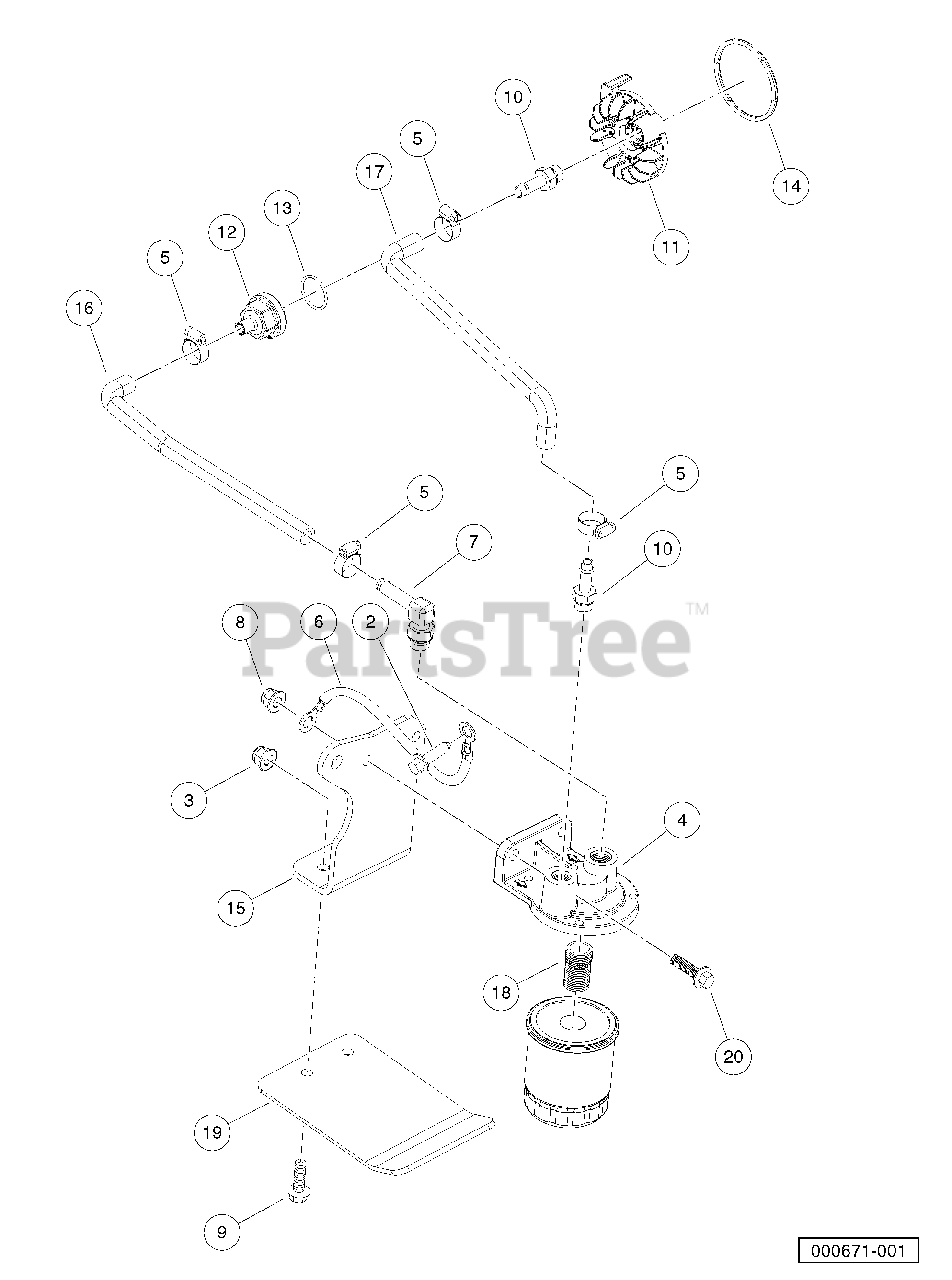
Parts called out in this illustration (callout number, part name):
1	Instl, Oil Fltr Adapter Fh680d
2	Screw, M8X1.25X30, Hex
3	Nut,m8,all Metal Lock
4	Bracket, Oil Filter Mount
5	Clamp, Hose
6	Wire Asm, #6 Blk, Awd, 325
7	Adapter, 90, 3/8 Tube
8	Lock Nut, Flg M8 X 1.25 Nylon
9	Bolt, M8 X 1.25 X 40 with Loctite
10	Adapter, 5/16 Hose
11	Adapter, Special, Oil Filter
12	Nut, Special, Hose Adapter
13	O-ring, 23.52 X 1.78mm
14	O-ring, Oil Filter Adapter
15	Bracket, Oil Filter, Fh680d
16	Hose, Formed, Oil, 5/16"
17	Hose, Formed, Oil, 5/16", Ret
18	Nipple, 3/4-16 X M20 X 1.5-6g
19	Guard, Oil Filter, Fh680d
20	Bolt, M8 X 1.25 X 30
